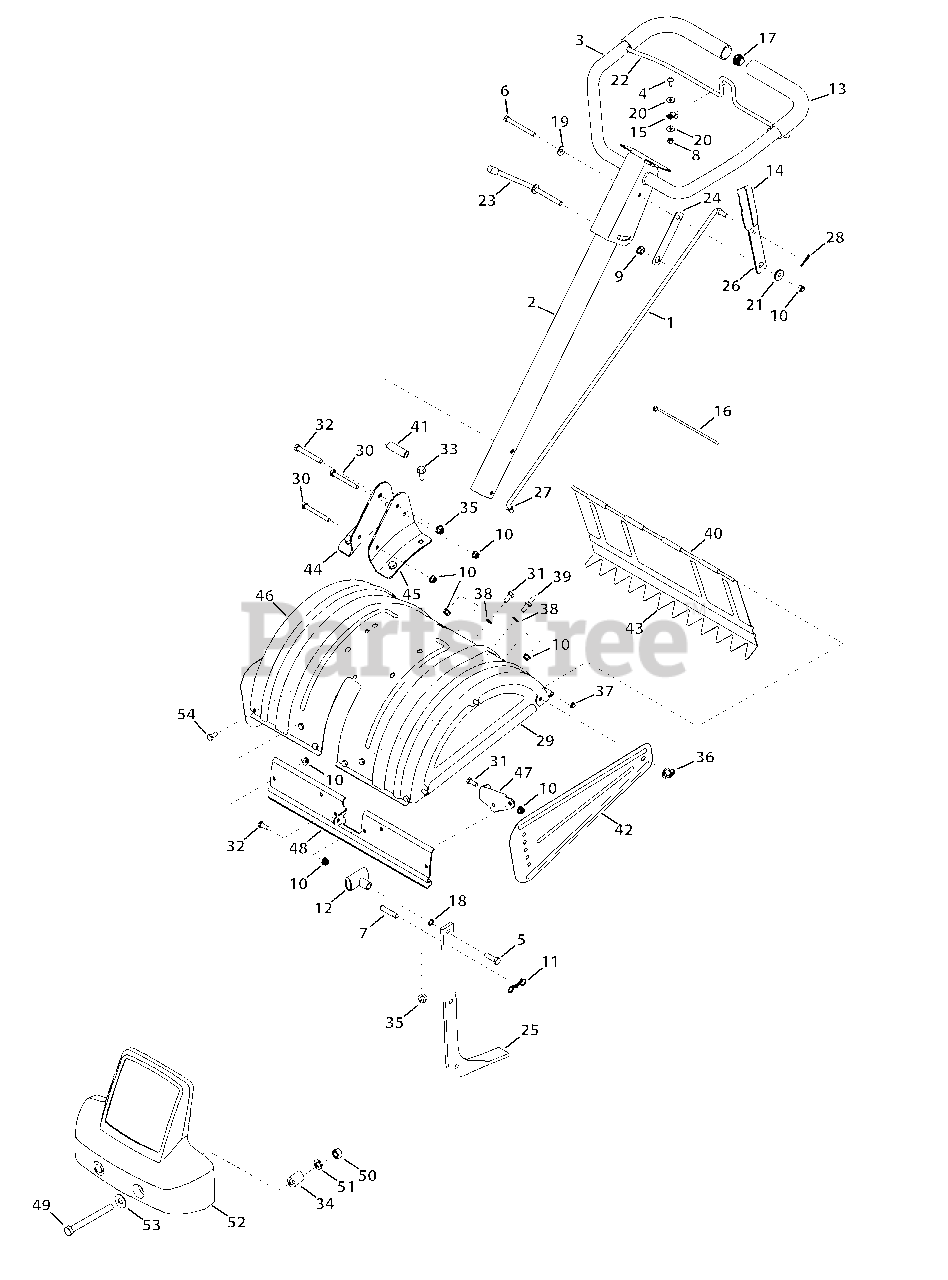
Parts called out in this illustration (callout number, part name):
1	Shift Rod
2	Lower Handle Tube Assembly
3	Upper Handle Assembly
4	Screw, 1/4-20 x 0.625
5	Hex Screw, 3/8-16:1.25
6	Hex Screw, 5/16-18 x 3.25
7	Clevis Pin, .375 X 1.75
8	Hex Lock Nut, 1/4-20
9	Flange Lock Nut, 3/8-24
10	Hex Lock Nut, 5/16-18
11	Cotter Pin
12	Small Tee Knob
13	Foam Grip, .970 x 11.0
14	Grip, .1875 x 1.00
15	Battery Clamp, 5/16
16	Cable Tie, 8.5
17	End Plug
18	Flat Washer, .385 x .620 x .033
19	Bell Washer, .340 x .872 x .060
20	Flat Washer, .260 x .720 x .060
21	Spacer, .50 x .190 x .360
22	Clutch Bail
23	Handle Adjustment Crank
24	Hex Nut Retainer Bracket
25	Tiller Depth Control
26	Shaft Rod Lever
27	Washer, .33 x .87 x .125
28	Cotter Pin, .072 x 1.12
29	End Cover Assembly
30	Hex Screw, 5/16-18 x 2.75
31	Hex Screw, 5/16-18 x 1.00
32	Hex Screw, 3/8-16 x 2.75
33	Hex Flange, 3/8-16 x .875
34	Hub, .636 x 1.00 x .94
35	Flange Lock Nut, 3/8-16
36	Wing Nut, 5/16-18
37	Speed Nut Cap, 1/4
38	Flat Washer, .344 x .62 x .033
39	Screw, Hex, 5/16-18 x .75
40	Tiller Flap Rod
41	Spacer, .322 x .625 x 2.00
42	Side Shield
43	Rear Tine Shield
44	RH Handle Mount Bracket
45	LH Handle Mount Bracket
46	Tine Shield
47	FRT Tine Shield Bracket
48	FRT Tine Shield Spacer Bracket
49	Hex Screw, 1/2-20 x 5.50
50	Hex Lock Nut, 1/2-20
51	Flat Washer, 1/2 x 1.25 x .10
52	Counterweight
